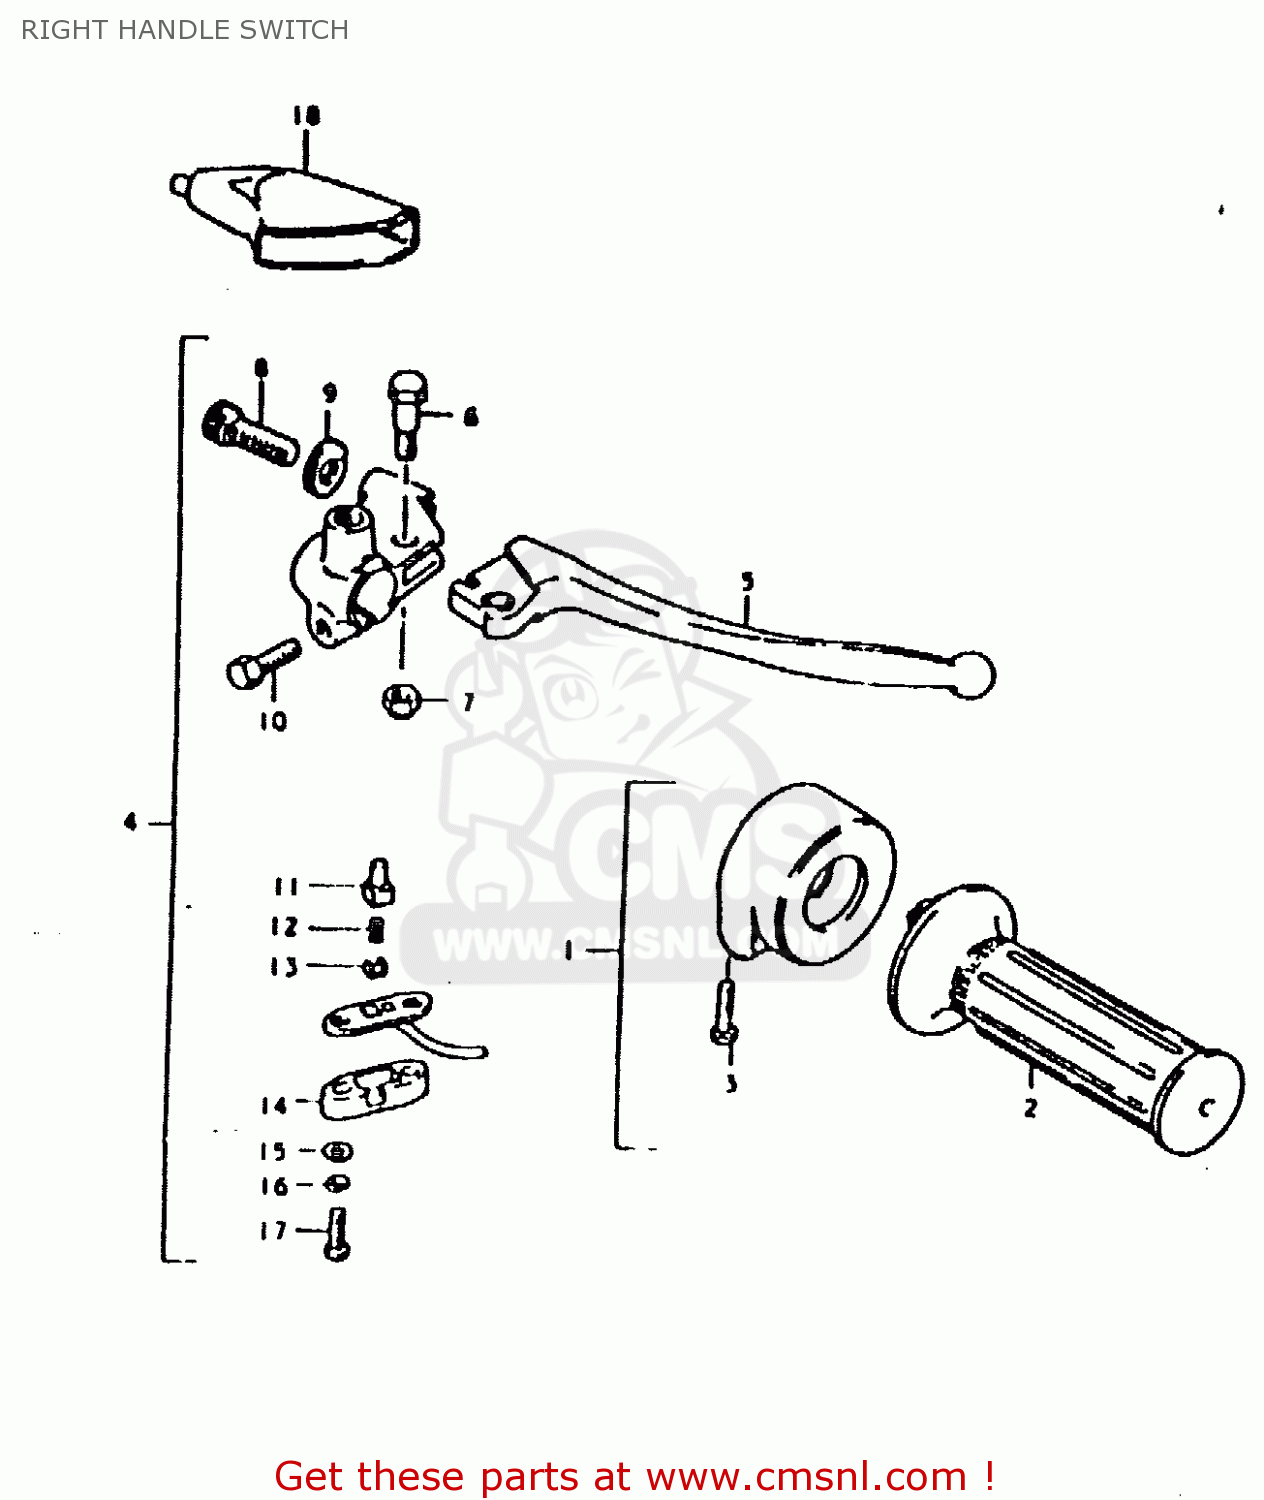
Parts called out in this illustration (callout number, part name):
1	GRIP ASSY, THROTTLE
2	GRIP,THROTTLE
3	SCREW
4	LEVER ASSEMBLY,BRAKE
5	LEVER,BRAKE
6	BOLT,LEVER
7	NUT
8	ADJUSTER,CABLE
9	NUT,CABLE ADJUSTER
10	BOLT
11	HOLDER
12	SPRING
13	PLATE
14	COVER,FR BK TERMINAL BASE
15	WASHER
16	LOCK WASHER
17	SCREW
18	COVER,CLUTCH LEVER
